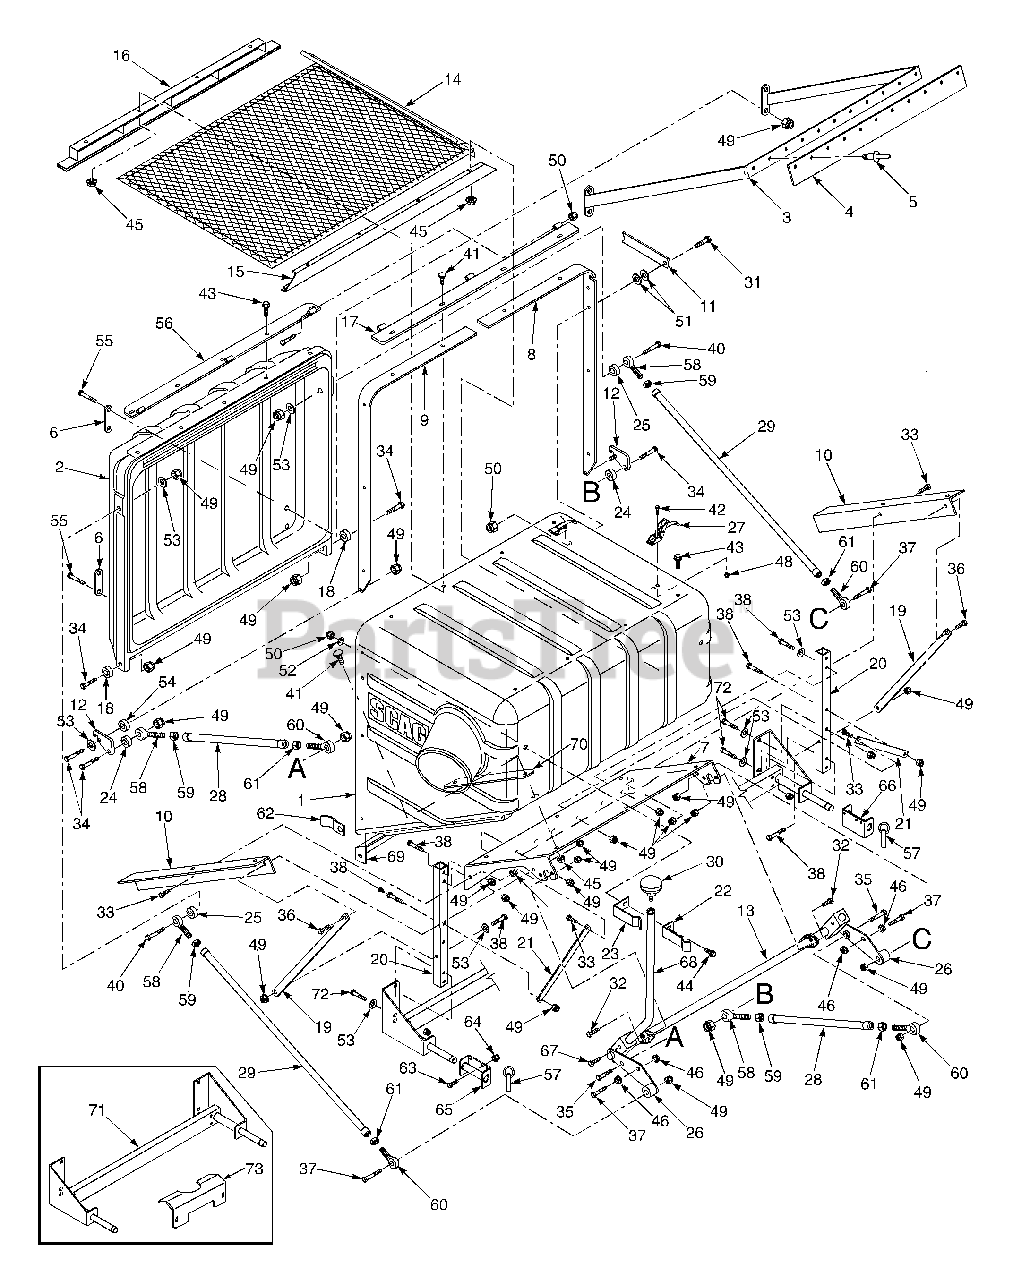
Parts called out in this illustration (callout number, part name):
1	Hopper, GC-STT-CS
2	Door, GC-CS
3	Sweeper Weldment, GC-CS
4	Pad, Rubber
5	Pop Rivet, 3/16 x .652
6	Plate, Stiffener
7	Support Frame, Hopper
8	Hinge Bracket, L.H.
9	Hinge Bracket, R.H.
10	Bracket, Hopper Support
11	Latch, Door Prop
12	Plate, Latch
13	Bellcrank Weldment, Upper
14	Debris Screen Weldment
15	Screen Support Weldment, Rear
16	Screen Support Weldment, Front
17	Hinge Weldment, Hopper
18	Spacer
19	Brace Stiffener, Short
20	Tube, Upright
21	Brace, Engine Mount
22	Latch, Dump Rod Inner
23	Latch, Dump Rod Outer
24	Spacer
25	Spacer
26	Spacer
27	Latch, Hood
28	Linkage Assembly, Lower
29	Linkage Assembly, Upper
31	Bolt, Hex Head 5/16-18 x 1-1/4
32	Bolt, Hex Head 3/8-16 x 3/4"
33	Bolt, Hex Head 3/8-16 x 1"
34	Bolt, Hex Head 3/8-16 x 1-1/2"
35	Bolt, Hex Head 3/8-16 x 1-3/4"
36	Bolt, Hex Head 3/8-16 x 1-1/4"
37	Bolt, Hex Head 3/8-16 x 2"
38	Bolt, Hex Head 3/8-16 x 2-1/4"
39	Bolt, Hex Head 5/16-18 x 3-1/2"
40	Bolt, Hex Head 3/8-16 x 3-1/2"
41	Bolt, Carriage 5/16-18 x 1"
42	Screw, #10-32 x 1/2"
43	Cap Screw, 5/16-18 x 3/4" Serr. Flan.
44	Cap Screw, 5/16-18 x 1" Serr. Flan.
45	Nut, 5/16-18 Serrated Flange
46	Nut, 3/8-16 Serrated Flange
47	Nut, 3/8-16 UNC Jam
48	Nut, #10-32 Elastic Stop
49	Nut, 3/8-16 Elastic Stop
50	Nut, 5/16-18 Elastic Stop
51	Washer, Special Wave
52	Washer, 5/16-.375 x .875 x .083 Flat
53	Washer, 3/8-.931 x .938 x .105 Flat
54	Bushing, Hopper Latch GC-CS
55	Bolt, Hex Head 3/8-16 x 3"
56	Hinge Weldment, Door
58	Rod End Male, 3/8-24 L.H. Thread
59	Nut, 3/8-24 UNF L.H. Thread
60	Rod End Male, 3/8-24 R.H. Thread
61	Nut, 3/8-24 UNF R.H. Thread
62	Alignment Bracket, GC-CS
63	Bolt, Hex Head 3/8-16 x 1"
64	Nut, 3/8-16 Elastic Stop
65	Hitch Bracket Weldment
66	Hitch Bracket Weldment, Floating
67	Bolt, Hex Head 5/16-18 1-3/4"
68	Rod, Dump Lever
69	Bracket, Lower Stiffener
70	Retainer Strip, Hopper
71	Frame Weldment
72	Bolt, Hex Head 3/8-16 x 3-3/4"
73	Support Bracket, Catcher
